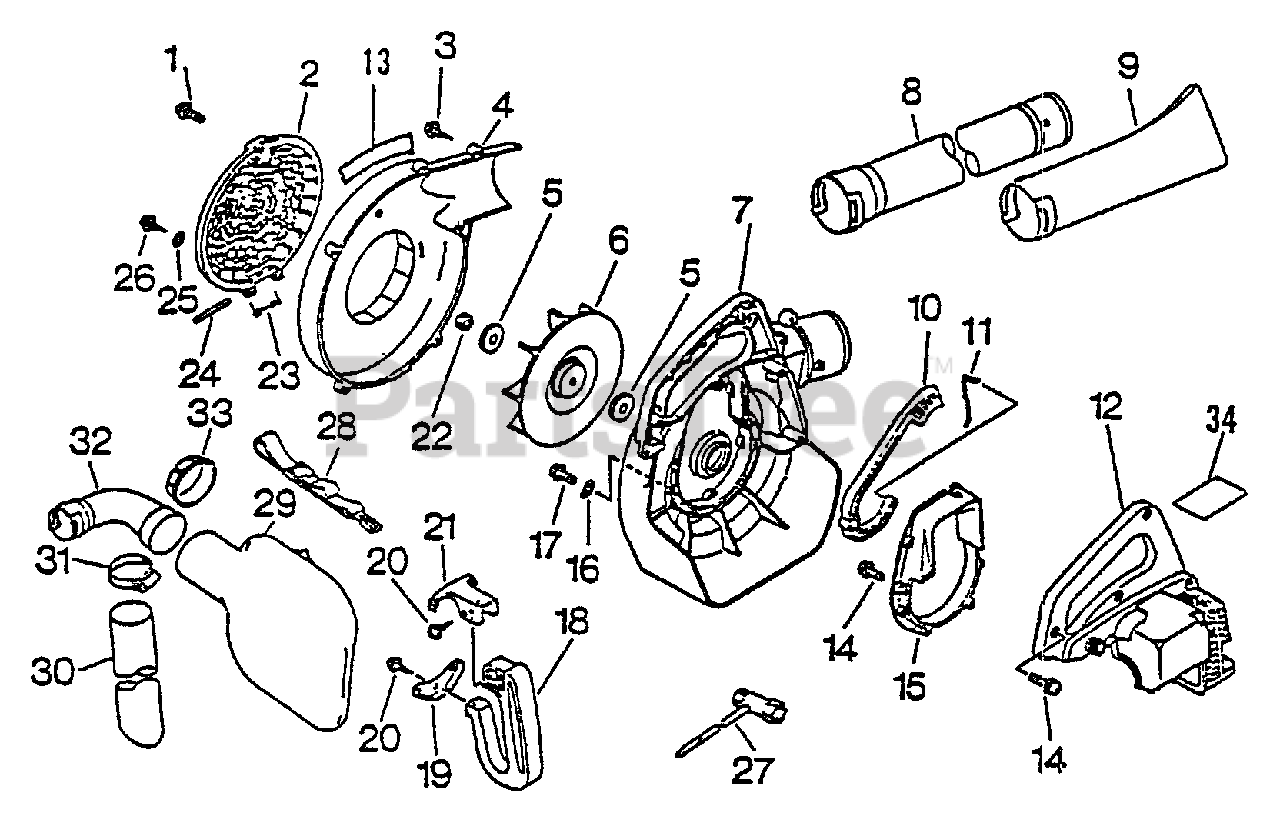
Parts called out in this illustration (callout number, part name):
1	THUMBSCREW
1	SCREW - 5X18
2	GUARD, DEBRIS
3	SCREW - 5X20 -- TAPPING
4	COVER, FAN - RIGHT
5	WASHER - 8
6	FAN
7	COVER, FAN - RIGHT
8	TUBE, BLOWER - STRAIGHT
9	NOZZLE - FAN HEAD
10	TRIGGER, THROTTLE
11	ROD, THROTTLE
12	COVER, ENGINE
13	LABEL - MODEL LBH-2100
14	SCREW - 4X18
15	BRACKET, ENGINE
17	SCREW - 4X22
18	HANDLE - REAR
19	BRACKET, HANDLE - LOWER
20	SCREW - 5X14
21	BRACKET, HANDLE - UPPER
26	SCREW - 5X14
27	T-WRENCH - 13X19mm
28	SHOULDER STRAP ASSY
29	BAG, DEBRIS
30	TUBE, VACUUM
32	TUBE, DEBRIS
34	LABEL - HOT SURFACE
